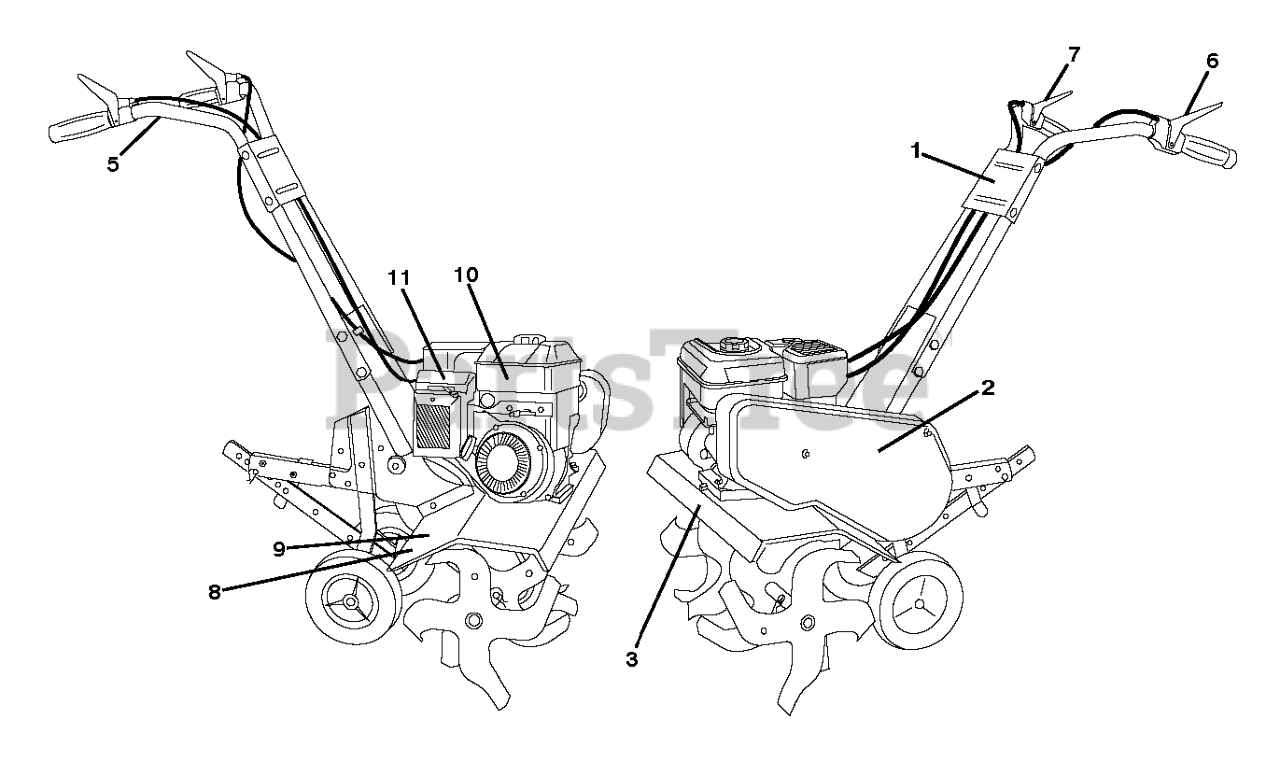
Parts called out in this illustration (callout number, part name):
1	DECAL.CONSOLE.DBBND.FT900.HUSQ
2	RP.DECAL.BADGE.170MM.TEXTLOGO
3	DECAL.TINESHIELD.FTT.26".HUSQ.
5	DECAL TI (2 2)
6	DECAL
7	DECAL
8	DECAL TI
9	DECAL.WARNING.SHLD.ENG/FR
10	DECAL.B&S.900.TANK.REF.276991
11	DECAL.B&S.900.A/S.C (279005)
